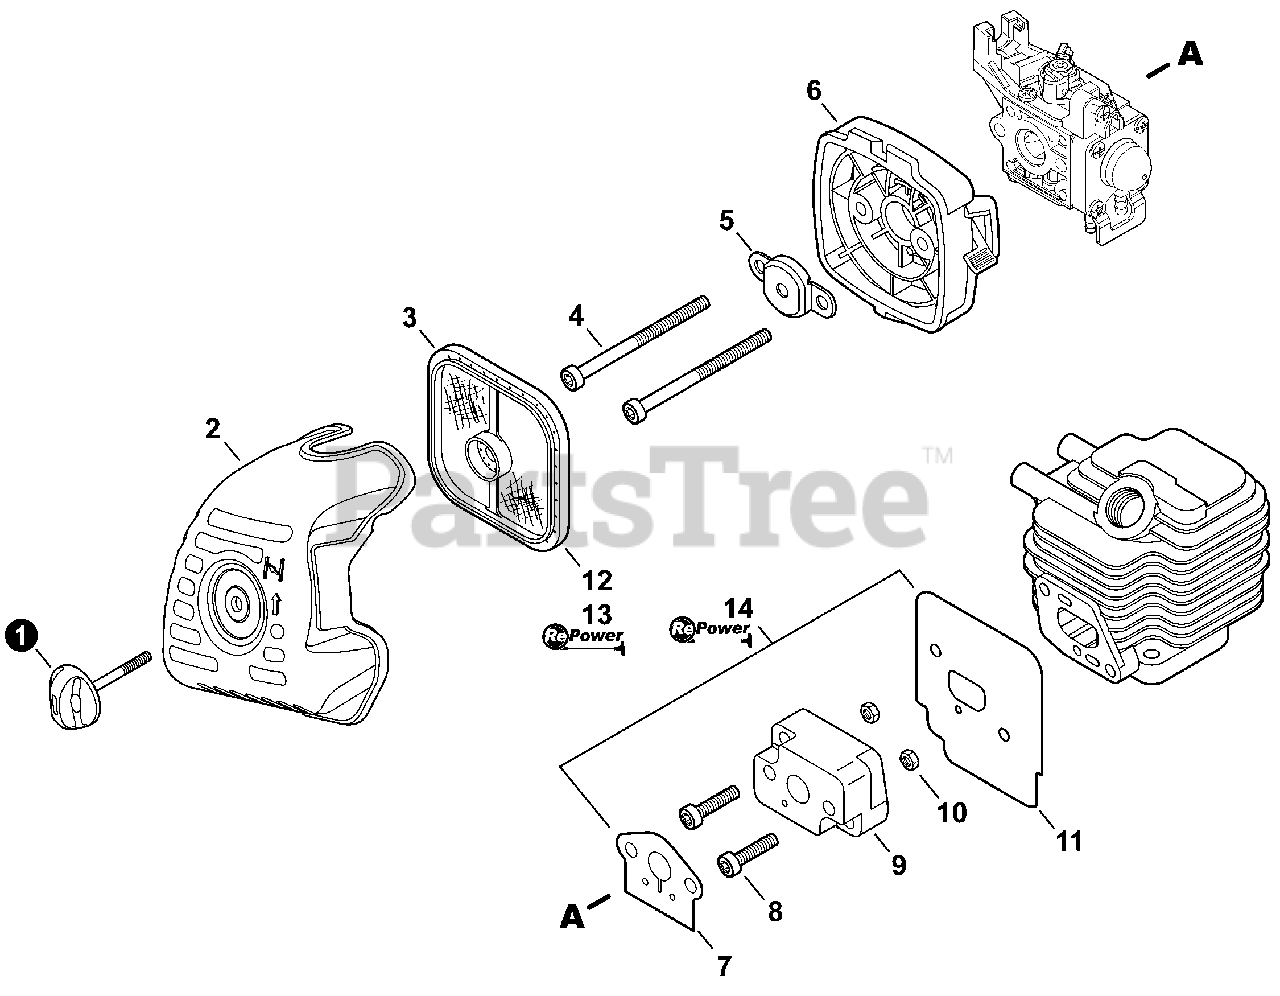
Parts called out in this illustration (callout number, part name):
1	THUMBSCREW
2	COVER, AIR FILTER
3	FILTER, AIR - DOUBLE LAYER
4	BOLT, TORX 5×65
5	PLATE, PREVENT
6	CASE ASSY, AIR FILTER
7	GASKET, INTAKE
8	BOLT, TORX 5×20
9	INSULATOR, INTAKE
10	NUT M5
11	HEAT SHIELD, INTAKE
12	TUNE-UP KIT - REPOWER
13	FILTER KIT - REPOWER
14	GASKET KIT: ENGINE, INTAKE, EXHAUST
